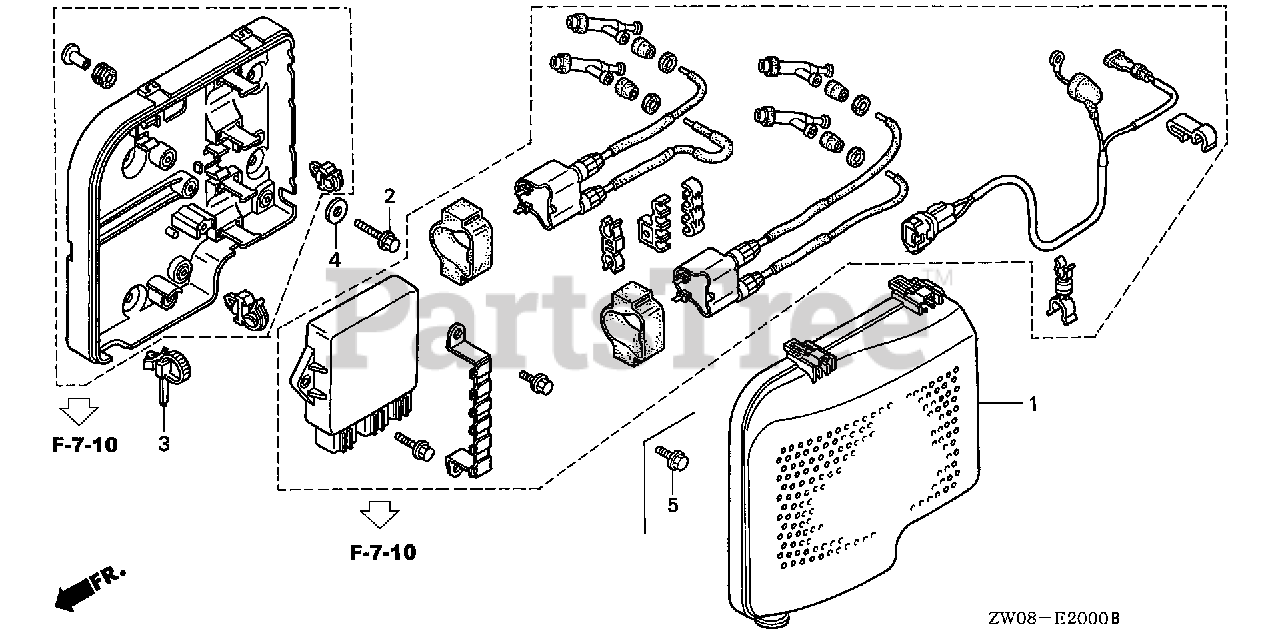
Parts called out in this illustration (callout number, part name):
1	COVER, IGNITION CONTROL MODULE (CDI)
2	BOLT, FLANGE (6X25)
3	STRAP, CABLE (118MM) *NH1L* (Honda Code 1170653). (BLACK)
4	WASHER, PLAIN (6MM)
5	BOLT, FLANGE (6X12)
